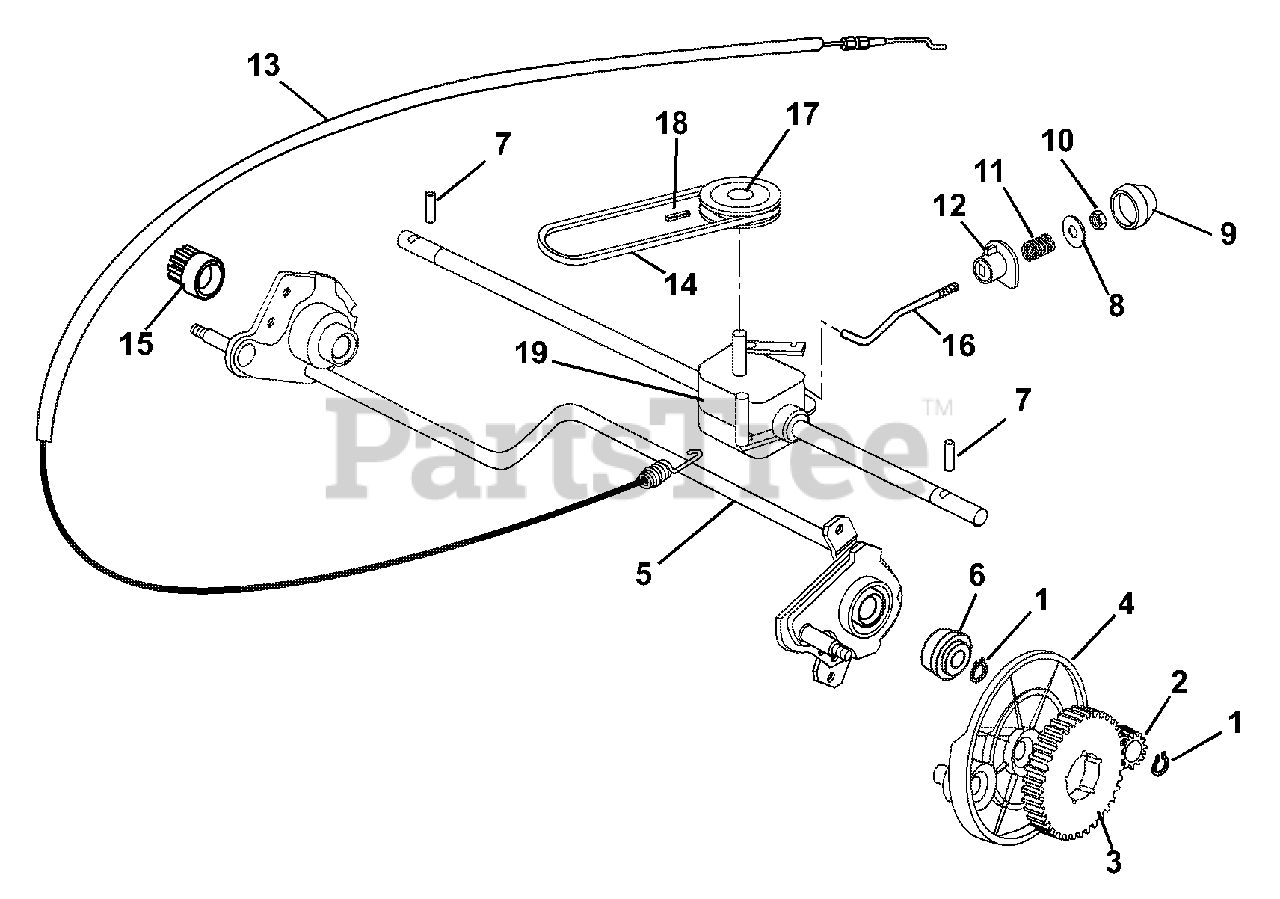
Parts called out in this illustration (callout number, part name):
1	SNAP RING
2	PINION, LEFT
3	GEAR, RING
4	PROTECTION, WHEEL
5	AXLE, REAR WHEEL
6	BEARING
12	BUSHING
13	CABLE, REAR DRIVE 3SPD IMPORT
14	V-BELT, 3 SPEED ALUM DECK
15	PINION, RIGHT
16	ROD, ADJUSTMENT LM 3SP IMPORT
17	PULLEY, 3 SPEED ALUM DECK
18	PIN
19	TRANSMISSION, W/PULLEY & PIN
